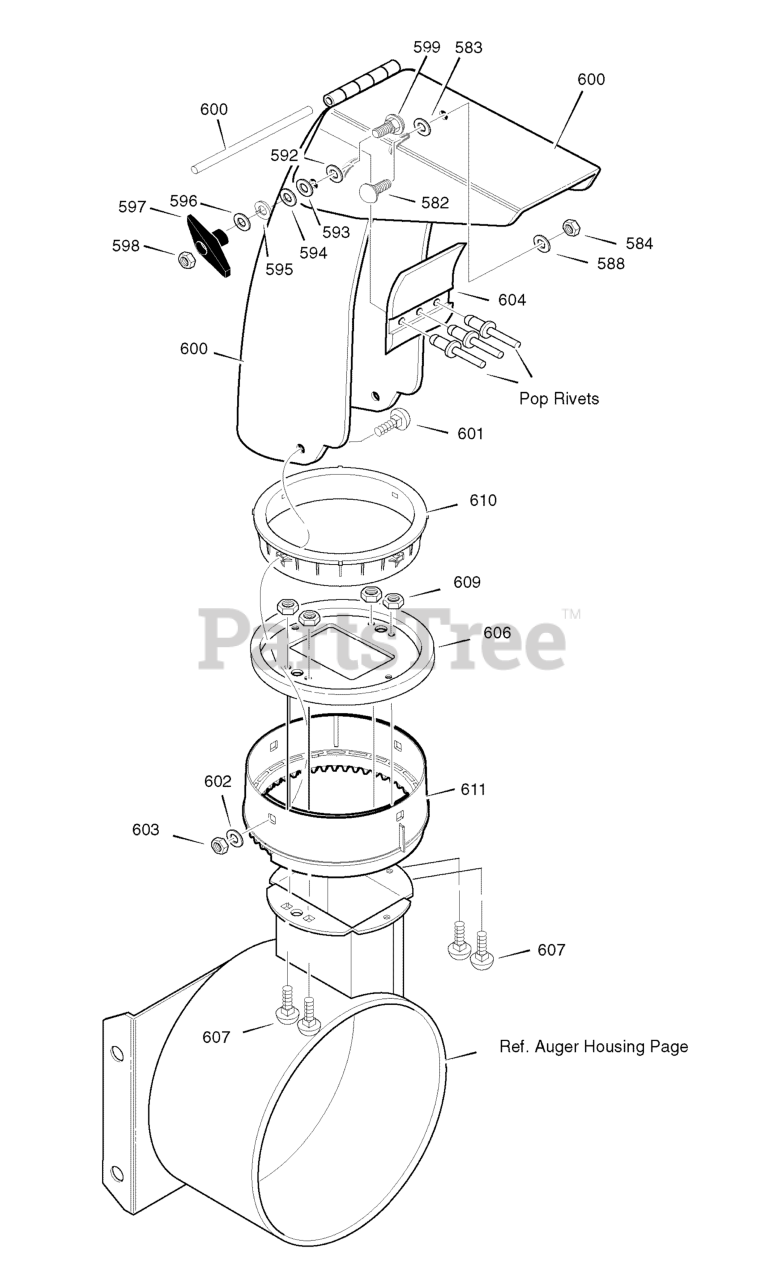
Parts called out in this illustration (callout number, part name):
582	BOLT, CARRIAGE 5/16-18 X .75
583	WASHER, PLASTIC
584	NUT, 5/16-18 REGHEX NYLOCK
588	WASHER, PLASTIC
592	WASHER, PLASTIC
593	WASHER, PLASTIC
594	WASHER, FLAT
595	WASHER, SPLIT
596	WASHER, FLAT
597	KNOB, T 3.00
598	NUT, 5/16-18 REGHEX
599	BOLT, 5/16-18 X 1.50
600	CHUTE ASSEMBLY AND GUARD
601	BOLT, 5/16-18 X 1.00
602	WASHER, FLAT
603	NUT, 5/16-18 HEXNYL
604	FLAP, CHUTE
606	CHUTE COLLAR
607	SCREW, 1/4-20 X 0.75
609	NUT, 1/4-20 HEX NYLOCK
610	RETAINER RING INNER
611	RETAINER RING OUTER
